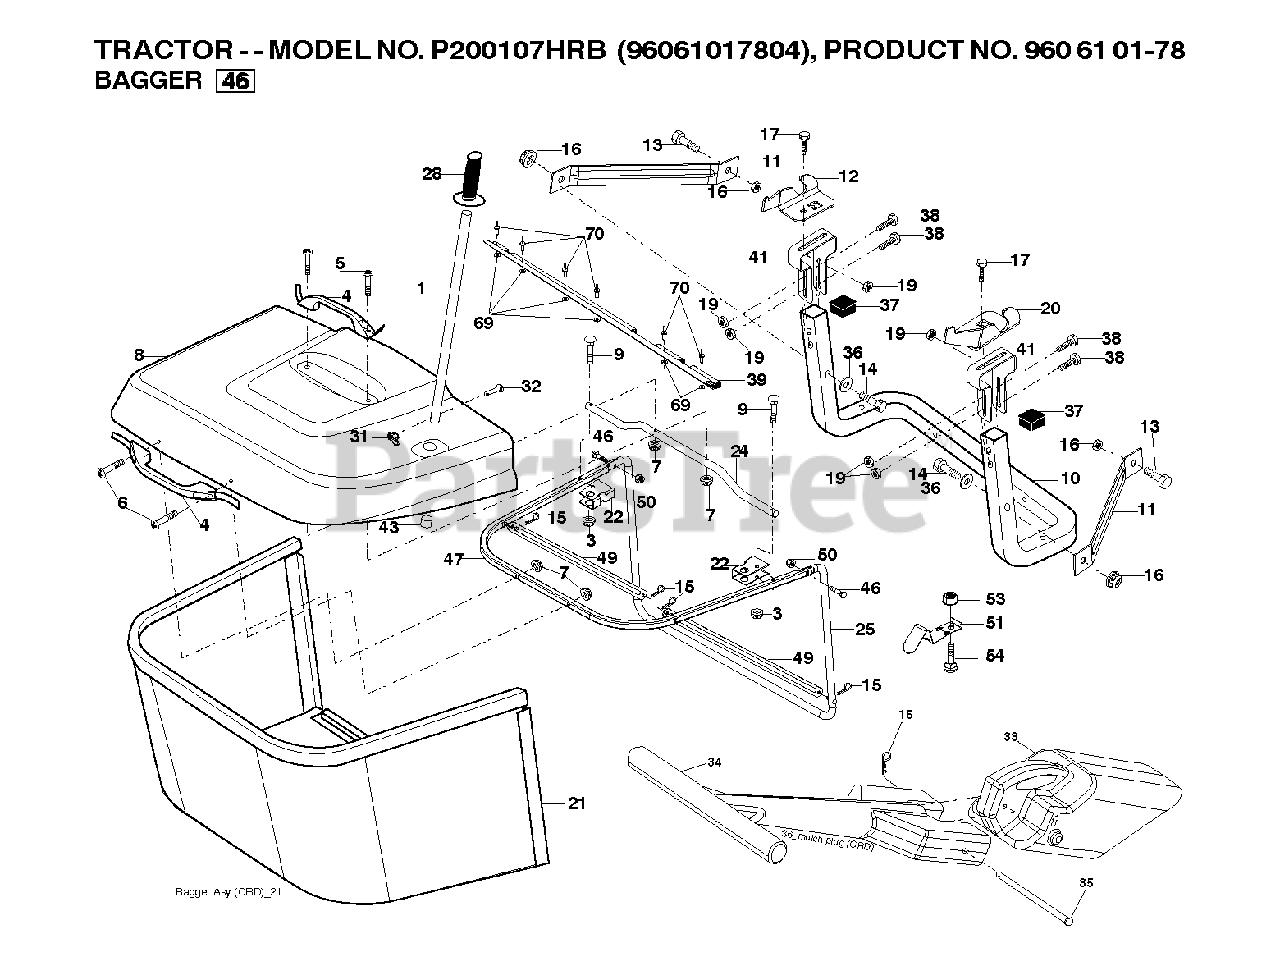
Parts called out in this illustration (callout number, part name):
1	TUBE.PNT.HDL.BAGGER.
3	NUT T
5	SCREW.PAN.HEAD
8	BAGGER.COVER.SEAL.ASM.CRD.428
11	BRACKET
14	BOLT-HEX EAK
15	RETAINER-SPRNG RB
16	NUT LOCK FLG 3/8-16 UNC
17	BOLT
19	NUT LOCK HEX FLANGE 5/16-18
20	BRKT.PIVOT.RH.CRD
21	BAGGER.ASM.CRD.2007
22	BRACKET.BAGGER.SD.
24	TUBE
28	GRIP.HANDLE.BLACK
31	RETAINER CLIP
32	RIVET,DRILLED
33	MULCHING.PLUG.1078.CRD.NON-TEX
35	PIN
38	BOLT.5/16-18X2.5
39	SEAL.BAGGER.CRD
41	BRACKET.BAGGER.SD.
43	PLUG, TUBING END
46	BOLT.CARRIAGE.5/16-18
50	NUT.71038.31-18.HEX.NYLOCK
53	NUT
54	BOLT
